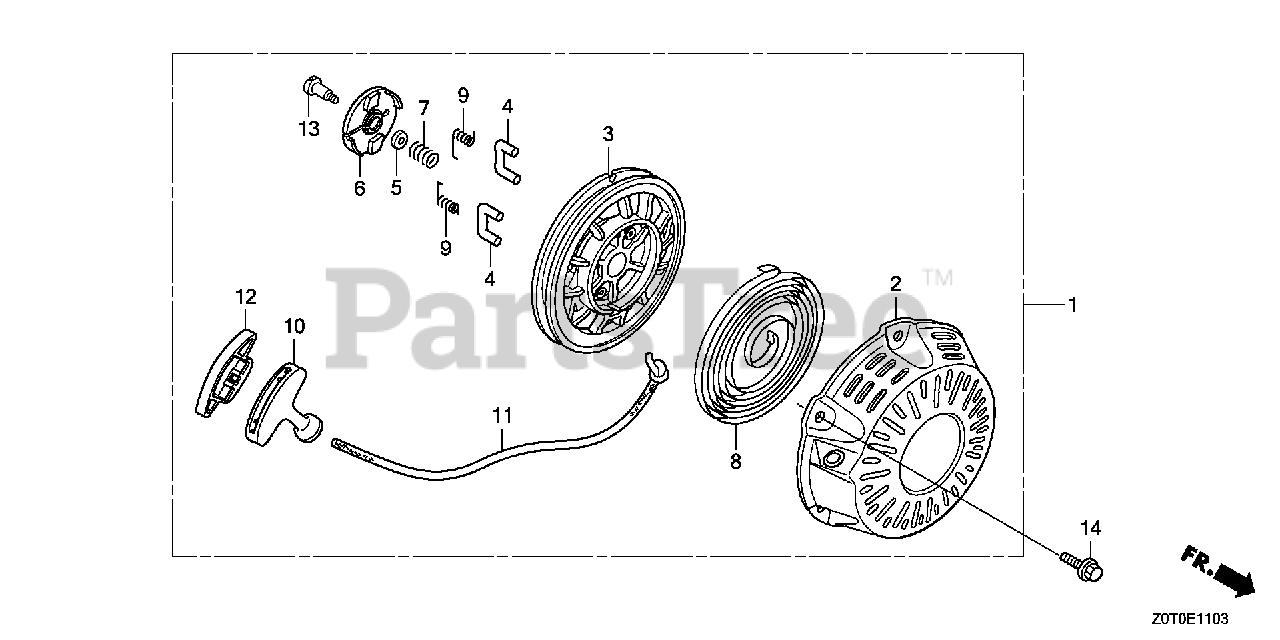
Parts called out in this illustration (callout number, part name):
1	STARTER ASSY., RECOIL *R280* (COO)(FOR U.S.A.) (POWER RED)
1	STARTER ASSY., RECOIL *NH1* (COO)(FOR U.S.A.) (BLACK)
2	CASE, RECOIL STARTER *R280* (POWER RED)
2	CASE, RECOIL STARTER *NH1* (BLACK)
3	REEL, RECOIL STARTER (BLACK)
4	RATCHET, STARTER
5	PLATE, FRICTION
6	GUIDE, RATCHET
7	SPRING, FRICTION
8	SPRING, RECOIL STARTER
9	SPRING, RETURN
10	KNOB, RECOIL STARTER
11	ROPE, RECOIL STARTER (#5X55")
12	KNOB, REINFORCEMENT
13	SCREW, SETTING
14	BOLT, FLANGE (6X8)
